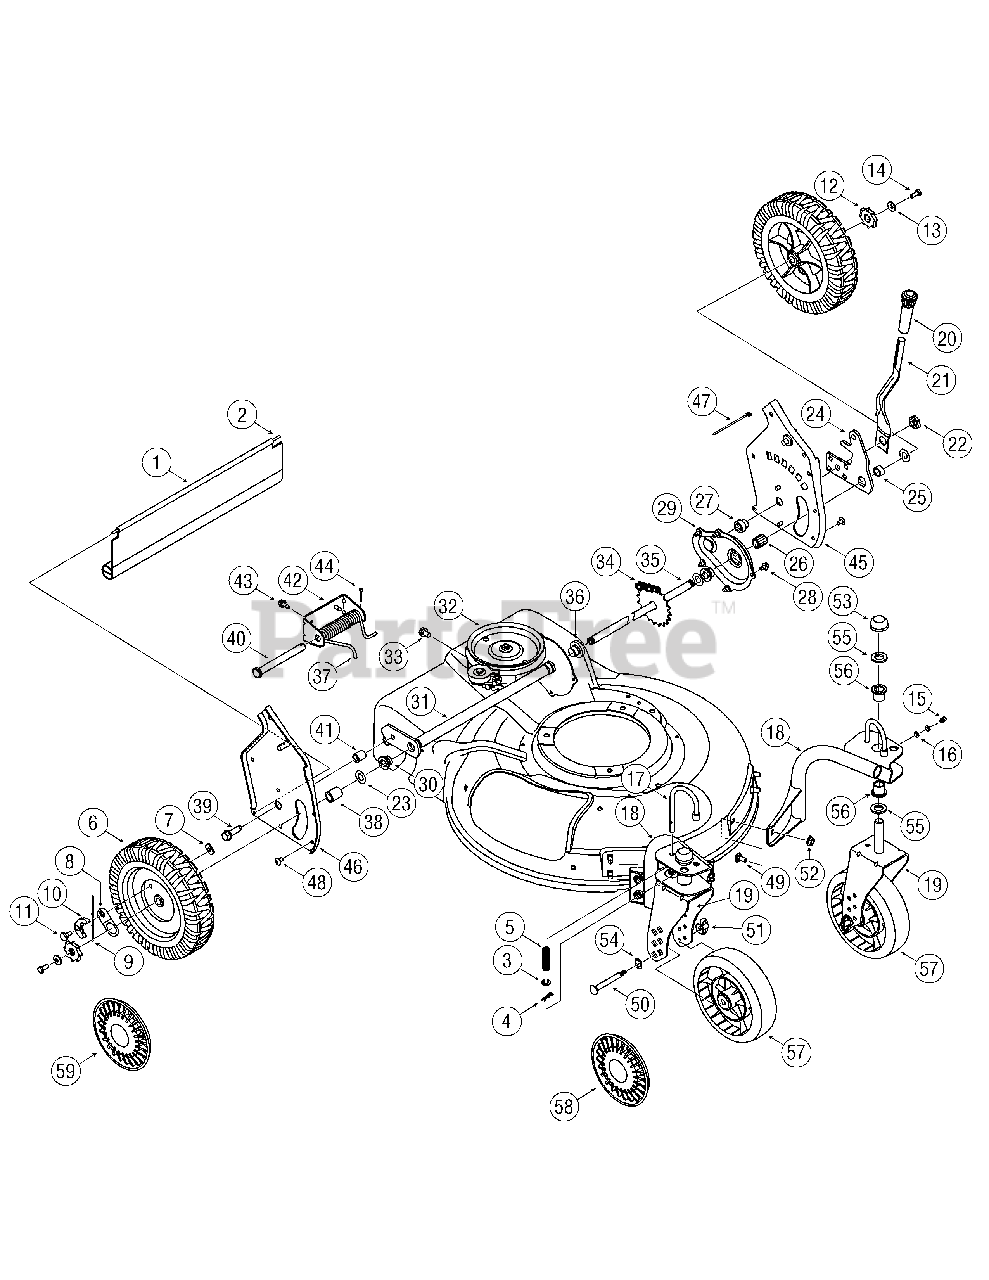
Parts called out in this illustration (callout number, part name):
1	Trail Shield
2	Trail Shield Wire
3	Flat Washer.330 ID x.630 OD
4	Cotter Pin
5	Compression Spring
6	Wheel 9 x 2.125
7	Top Lock Tab Weld Nut 1/4-20
8	Ratchet Pawl Plate
9	Plastic Spring Ratchet
10	Pawl RH
10	Pawl LH
11	Shoulder Screw.340 ID x.285 OD
12	Wheel Ratchet
13	Bell Washer.265 ID x.75 OD
14	Hex Cap Screw 1/4-20 x.620
15	Grease Fitting
16	Flat Washer.203 ID x.403 OD
17	Wheel Pin Lock
21	Spring Lever
22	Shoulder Nut.825 x .165 Lg.
23	Flat Washer .508 ID x 1.0 OD
25	Spacer .510 ID x .70 OD
26	Sleeve Bearing .504 ID x .830
27	Shoulder Spacer
28	Tap Screw 1/4-20 x .375
32	Transmission Assembly Complete
33	Hex Screw 5/16-18
34	Chain
35	Rear Axle Assembly
36	Flange Bearing .506 ID x .750 Lg
37	Torsion Spring
38	Spacer .550 ID x .750 OD
39	Screw 3/8-16 x .25
40	Clevis Pin .50 Dia x 4.82 LG
41	Spacer .385 ID x .624 OD
44	Cotter Pin
48	Screw 1/4-14 x.500
49	Carriage Bolt 5/16-18 x.62
50	Caster Axle
51	Wing Nut
52	Flange Lock Nut 5/16-18
53	Push Cap
54	Wave Washer.531 ID x.781 OD
55	Flat Washer.640 ID x 1.12 OD
56	Flange Bearing
57	Wheel 7 x 2
58	Hubcap - Spoke w/ Hole
59	Hubcap - Radial Spoke
